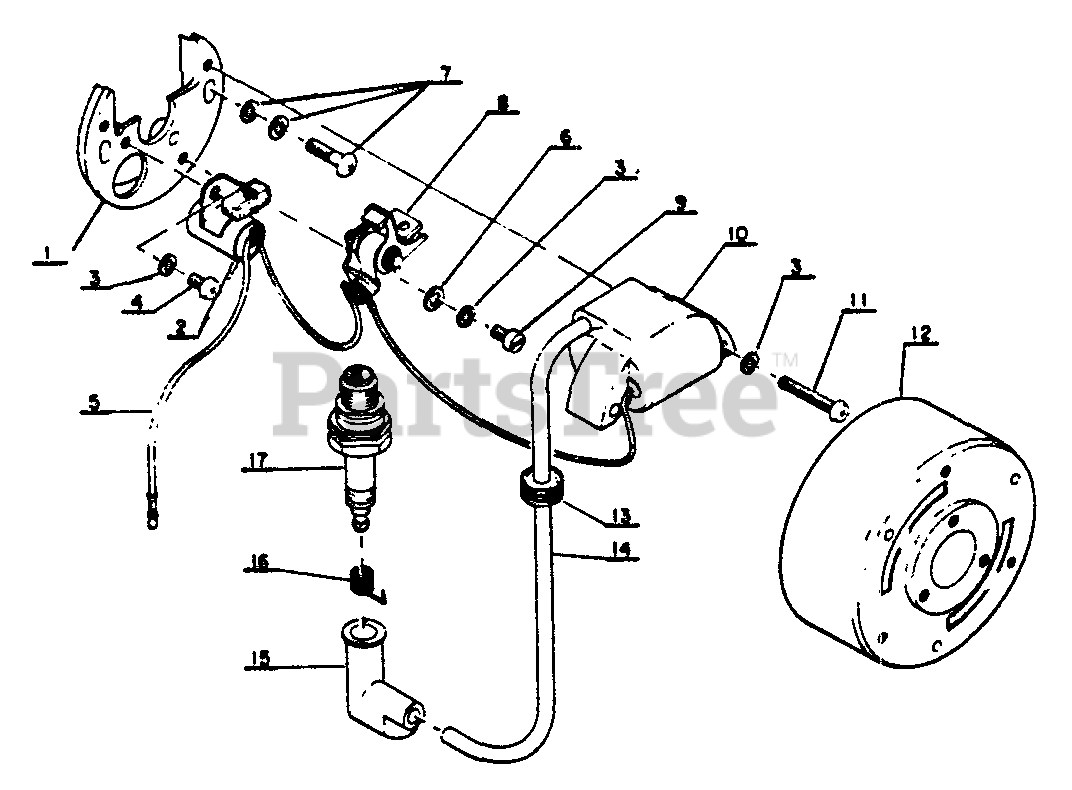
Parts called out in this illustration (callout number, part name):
1	PLATE, STATOR
2	CONDENSER
3	WASHER, SPRING 4 MM
4	SCREW 4×8
6	WASHER 4 MM
7	SCREW 4×16
8	CONTACT POINT SET
9	SCREW 4×8
10	COIL, IGNITION
11	SCREW 4×20
12	FLYWHEEL
13	RUBBER BUSH
15	CAP, SPARK PLUG
16	TERMINAL, SPARK PLUG CAP
17	SPARK PLUG
